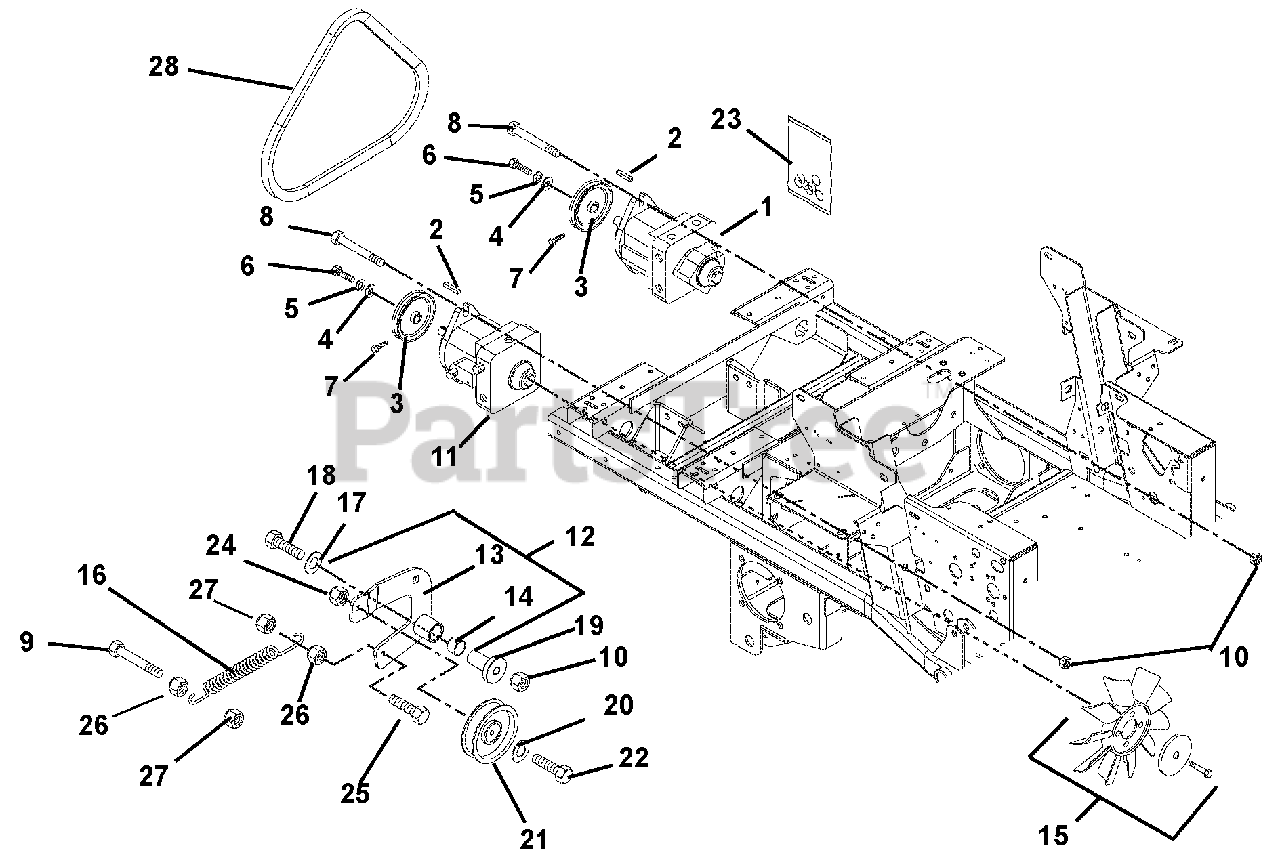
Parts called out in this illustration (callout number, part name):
1	PUMP - HYDRAULIC RTN W/AUX
2	KEY, SQ 5 X 5 X 30MM PLAIN
3	SHEAVE - POLY-V .671 X 4.125
4	WSHR-FL-STL .281X1.000X.063
5	@WSHR-LK .25X.062 REG YWZC
6	@BLT-HEX M6-1X16 YWZC
7	SCR-SKH .25-20 X .50 PH & OIL
8	@BLT-HEX .50-13X1.50 GR5 YWZC
9	@BLT-HEX .31-18X2.50 GR5 YWZC
10	@NUT-LK-TOP-FLG .50-13 YWZC
11	PUMP-HYD RTN THRU SHAFT F/FAN
12	ASSEMBLY, IDLER ARM
13	WMT, IDLER ARM
14	BSHG, 1.00 X 1.125 X 1.937
15	FAN KIT, HYDROGEAR 70618
16	SG-TENS .135X.69X5.75 WLD 150
17	@WSHR-FL-STL.563X1.38X.109YWZC
18	@BLT-HEX .50-13X3.50 GR5 YWZC
19	BEARING, PEDESTAL
20	@WSHR-FL-STL.406X.812X.065 YWZ
21	ASM, IDLER 4"
22	@BLT-HEX .38-16X2.00 GR5 YWZC
23	KIT, PUMP SEAL (BDP-21L)
24	@NUT-LK-TOP-FLG .38-16 YWZC
25	@BLT-HEX .31-18X1.25 GR5 YWZC
26	@NUT-HEX .31-18 YWZC
27	@NUT-LK-TOP-FLG .31-18 YWZC
28	POLY V-BELT, K-5 RIBS
